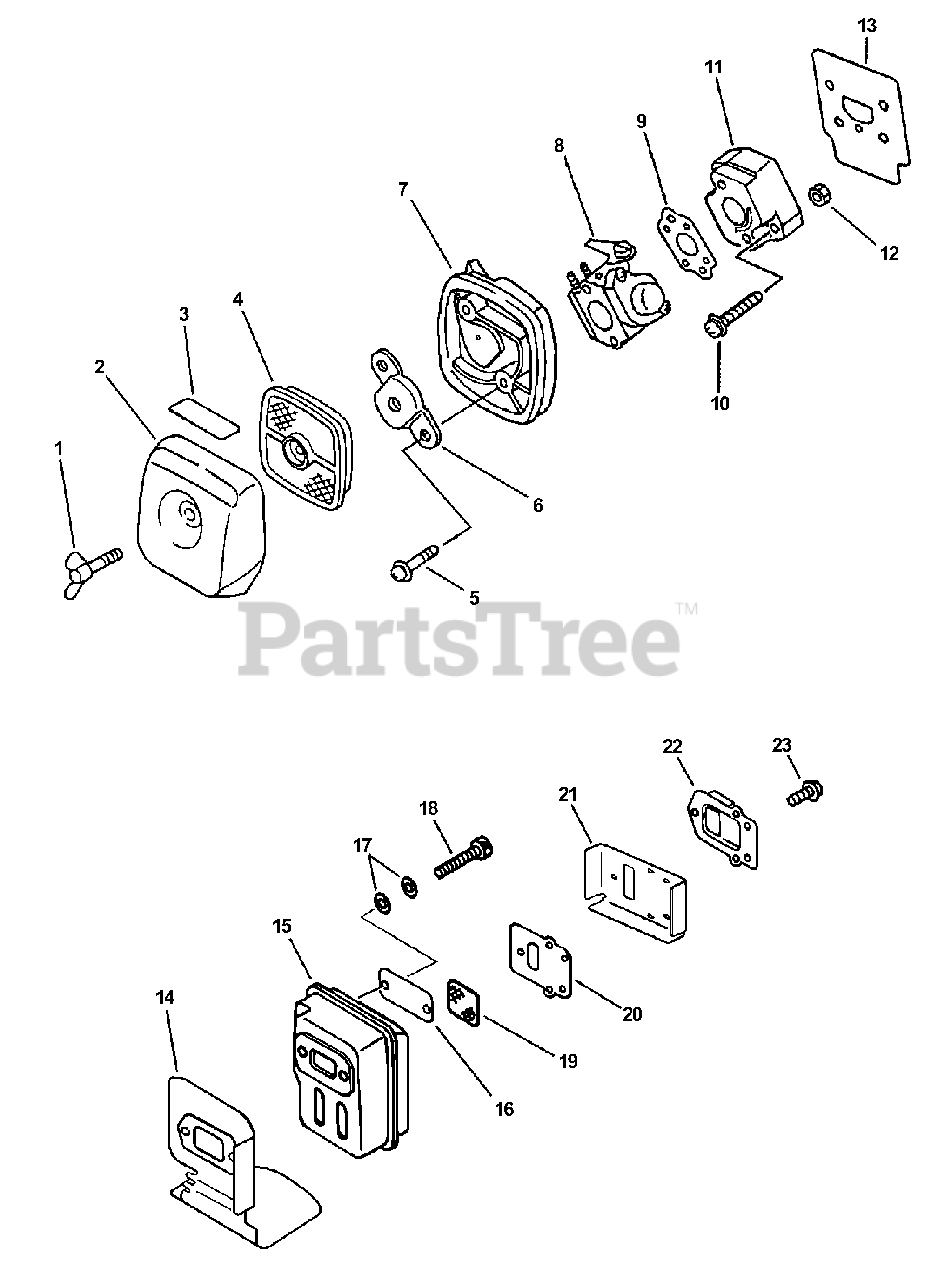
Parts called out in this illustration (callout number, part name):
1	THUMBSCREW
2	COVER, AIR FILTER - GRAY
3	LABEL - CHOKE
4	FILTER, AIR - SINGLE LAYER
5	SCREW - 5X65
6	PLATE, PREVENT
7	CASE, AIR FILTER - GRAY
8	CARBURETOR C1U-K58
9	GASKET, INTAKE
10	SCREW - 5X20
11	INSULATOR, INTAKE
13	SHIELD, INTAKE
14	SHIELD, EXHAUST
15	MUFFLER
17	WASHER - CONICAL
18	SCREW - 5X55
19	SCREEN, SPARK ARRESTOR
20	GASKET, EXHAUST
21	GASKET, EXHAUST
22	GUIDE, EXHAUST
23	SCREW - 4X10
